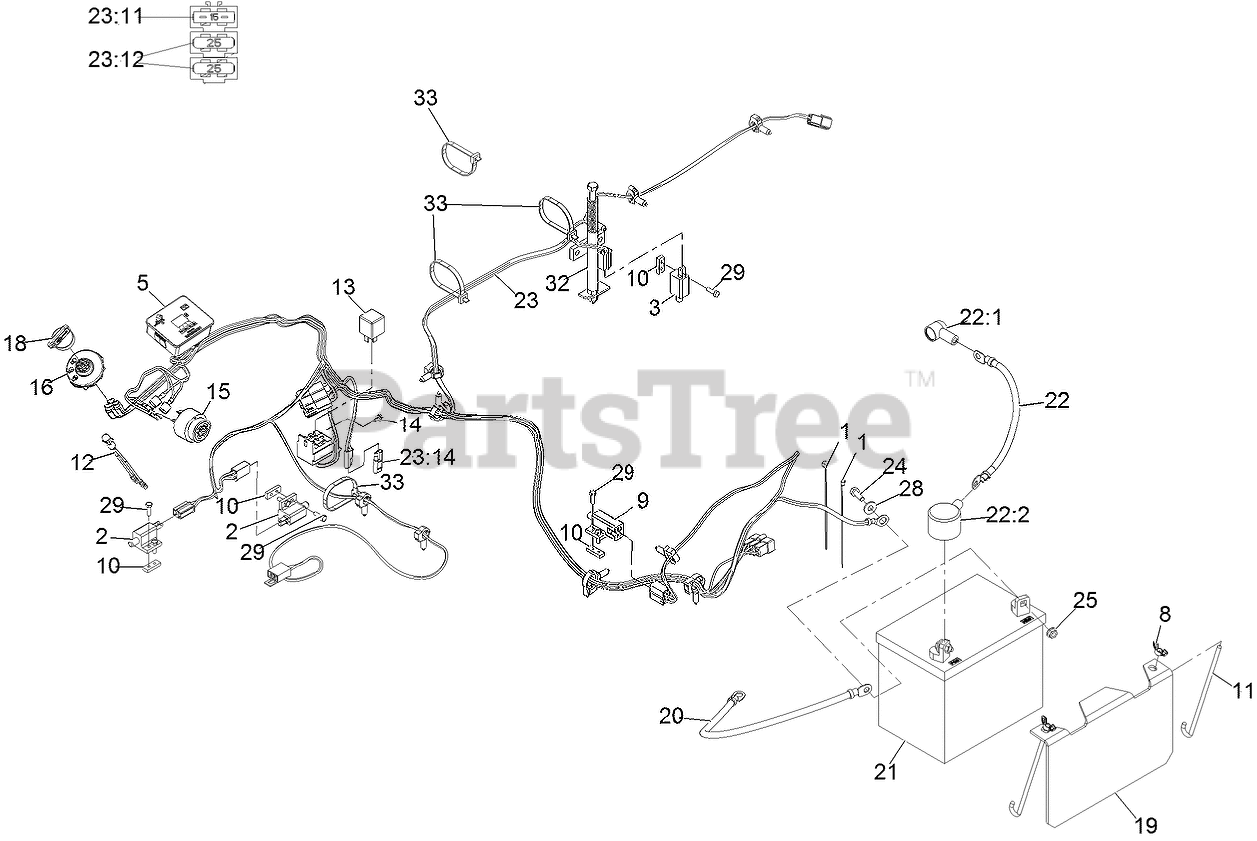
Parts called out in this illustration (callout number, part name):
1	TIE-CABLE
2	SWITCH-OPEN, NORMALLY
3	SWITCH-CLOSED, NORMALLY
5	HOUR METER ASM
8	WINGNUT
10	PLATE-TAPPED
11	BOLT-HOLDDOWN
12	INDICATOR-LED, RED
14	SCREW-HWH
15	ALARM-TONE, DUAL
16	SWITCH-IGNITION
18	KEY-IGNITION
19	HOLD DOWN-BATTERY
20	CABLE-BATTERY, NEGATIVE
21	Battery
22	CABLE-BATTERY, POSITIVE
22:1	INSULATOR-SOLENOID
22:2	INSULATOR-BATTERY
23	HARNESS-WIRING
23:11	FUSE-BLADE, 15 AMP
23:12	FUSE-BLADE, 25 AMP
23:14	CAP-PLUG
24	SCREW-HH
28	WASHER-FLAT
32	HOPPER SWITCH ACTUATOR AS
33	TIE-CABLE
